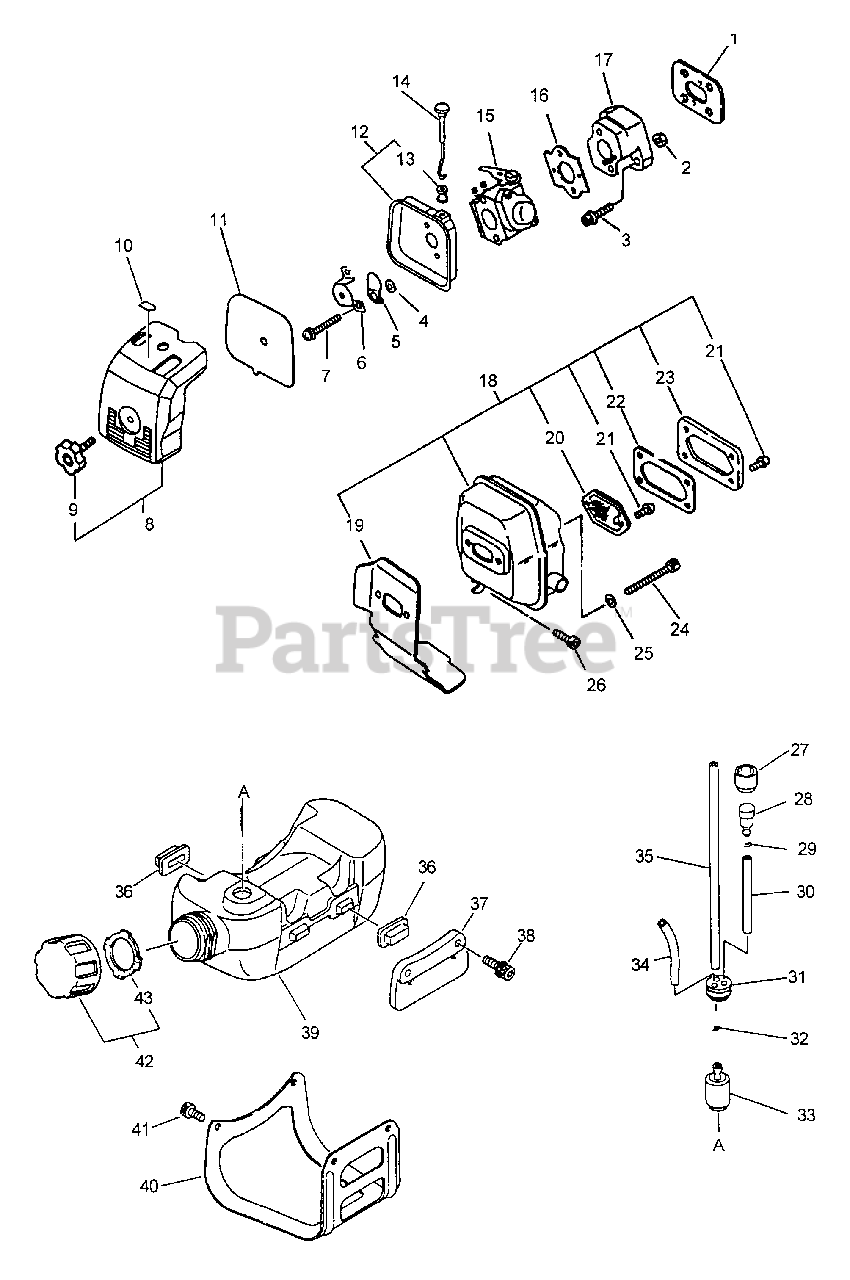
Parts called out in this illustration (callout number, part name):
1	GASKET, INTAKE
2	NUT M5
3	BOLT 5×25
4	WASHER 5.2×8×0.8T
5	SHUTTER, CHOKE
6	PLATE, PREVENT
7	BOLT 5×57
8	AIR FILTER COVER ASSY
9	THUMBSCREW
10	LABEL, CHOKE
11	FILTER, HEAVY-DUTY AIR
12	CASE ASSY, AIR FILTER
13	GROMMET, CHOKE
14	ROD, CHOKE
15	CARBURETOR - WT-418A
16	GASKET, CARBURETOR
17	INSULATOR, INTAKE
18	MUFFLER ASSY
19	GASKET, MUFFLER
21	SCREW 4×10
22	GASKET, EXHAUST
23	LID, MUFFLER
24	BOLT 5×60
25	WASHER, FLAT 5.5×10×0.8
26	BOLT 5×12
27	HOLDER, VENT
28	VENT ASSY
30	PIPE, FUEL VENT 3×5×50
31	GROMMET, FUEL
32	CLIP 6 MM
33	FILTER, FUEL
34	PIPE, FUEL RETURN 3×6×90 MM CLEAR
35	PIPE, FUEL 3x-5x-180
36	CUSHION, FUEL TANK
37	BRACKET, FUEL TANK
38	BOLT 5×20
39	TANK, FUEL
40	GUARD, FUEL TANK
41	BOLT 5×12
42	CAP ASSY, FUEL
43	GASKET, FUEL CAP
